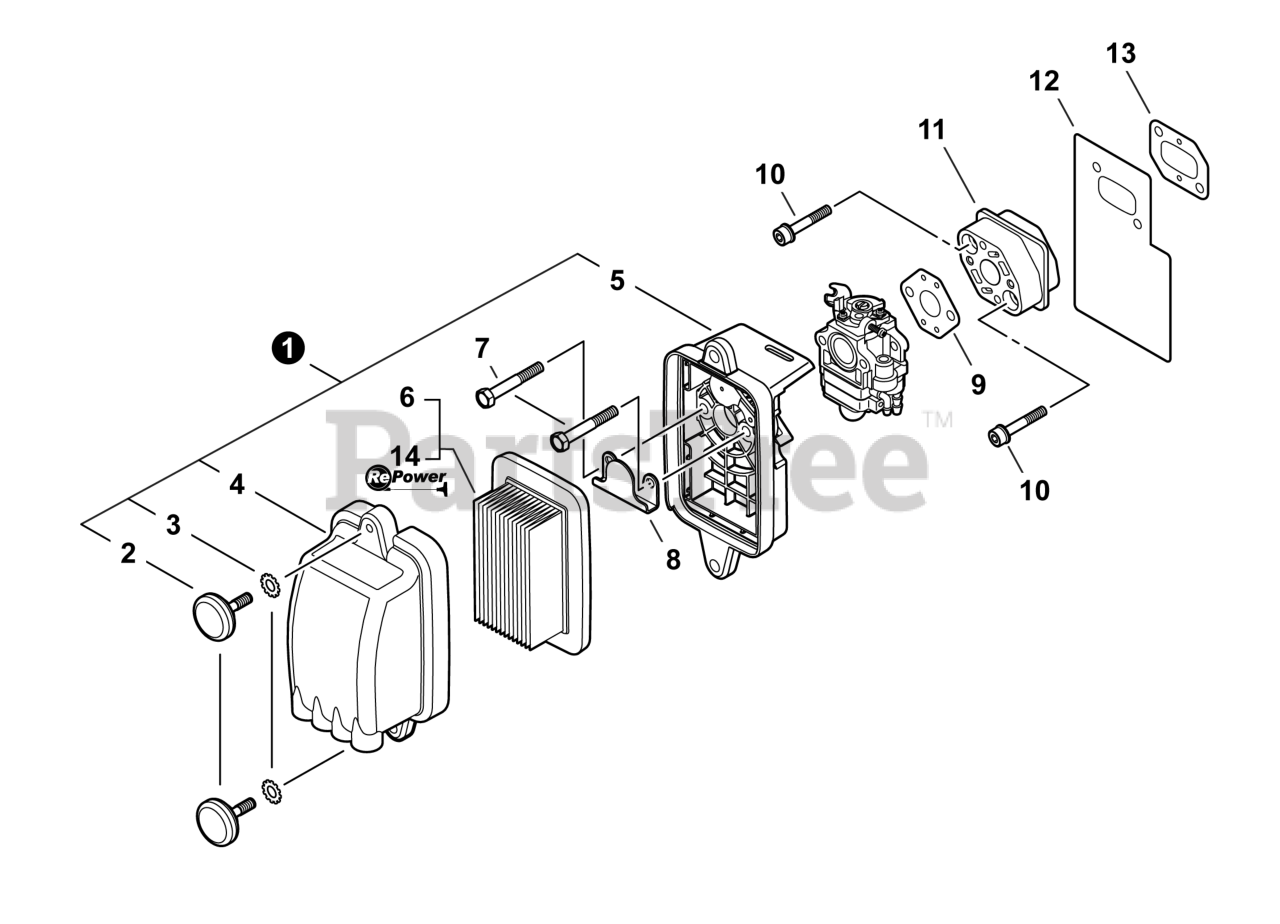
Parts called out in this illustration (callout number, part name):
1	FILTER KIT, AIR
2	THUMBSCREW
3	WASHER, LOCK
4	COVER, AIR FILTER
5	CASE ASSY, AIR FILTER
6	FILTER, AIR
7	BOLT 5×55
8	PLATE, PREVENT
9	GASKET, INTAKE
10	BOLT, FLANGE 5X25
11	INSULATOR, INTAKE
12	HEAT SHIELD, INTAKE
13	GASKET, INTAKE
14	TUNE-UP KIT - REPOWER
